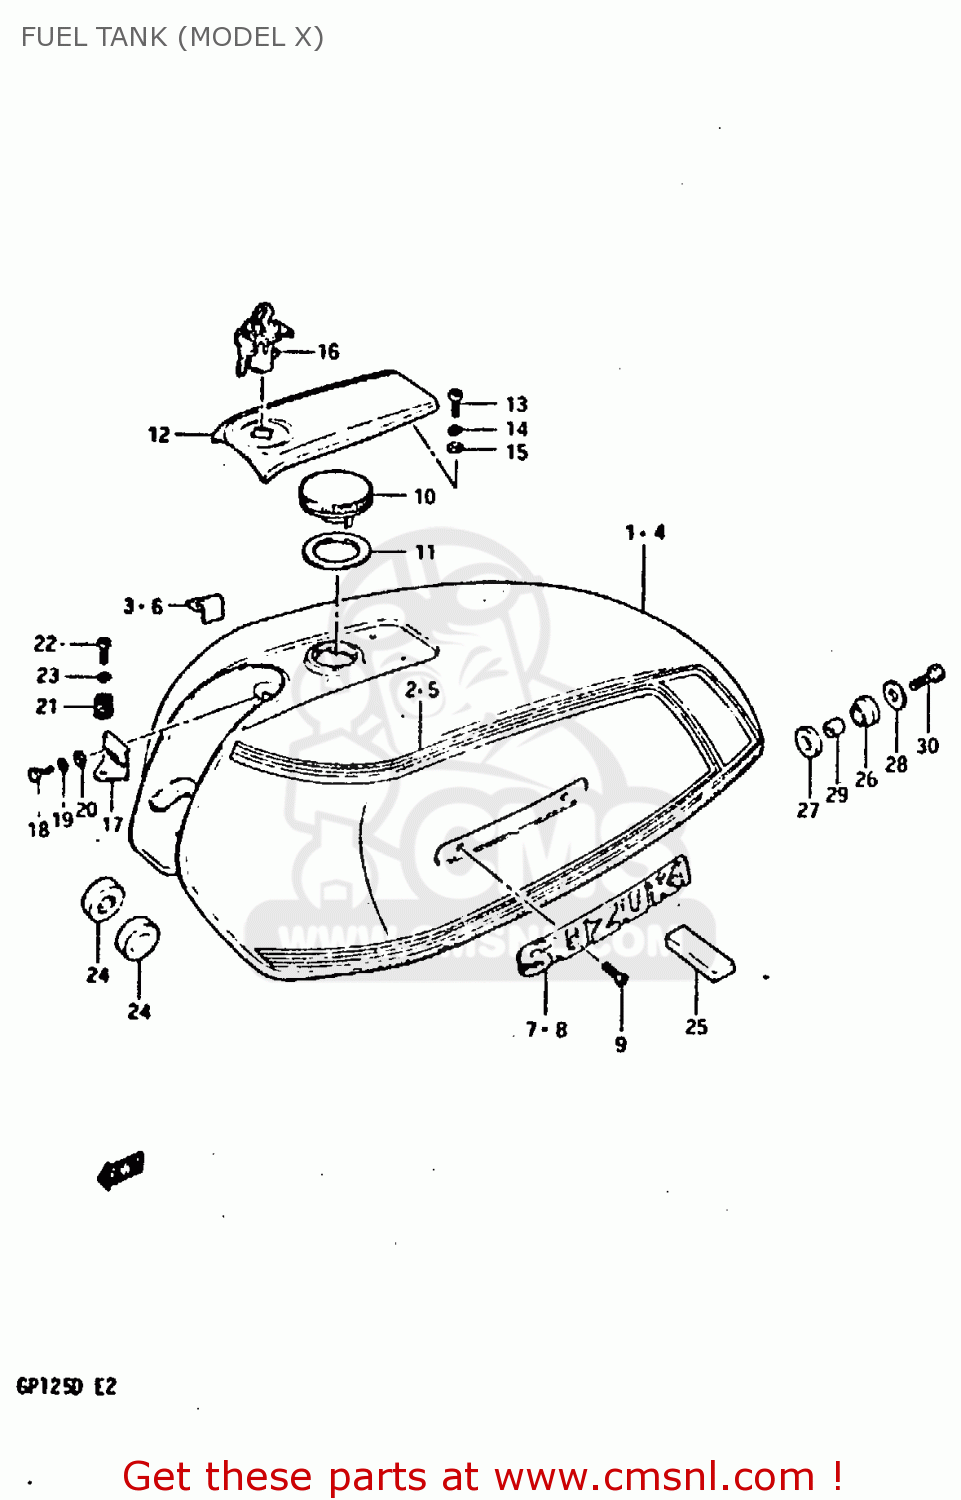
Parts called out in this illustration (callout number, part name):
1	TANK, FUEL (RED)
2	TAPE SET
3	CUSHION,FUEL TANK FR COVER
4	TANK, FUEL (BLUE)
5	TAPE SET
6	CUSHION,FUEL TANK FR COVER
7	EMBLEM,FUEL TANK
9	SCREW 3X6
10	CAP,FUEL TANK
11	GASKET (NAS)
12	COVER,FUEL TANK FR
13	BOLT
14	LOCK WASHER
15	WASHER
16	LOCK,FUEL TANK FR COVER
17	HOLDER,FUEL TANK FRONT COVER
18	BOLT
19	LOCK WASHER
20	WASHER
21	SPRING
22	SCREW
23	LOCK WASHER
24	CUSHION
25	CUSHION
26	CUSHION
27	CUSHION
28	WASHER (8.5X29X1.6)
29	SPACER (8.2X12X17)
30	BOLT (8X30)
